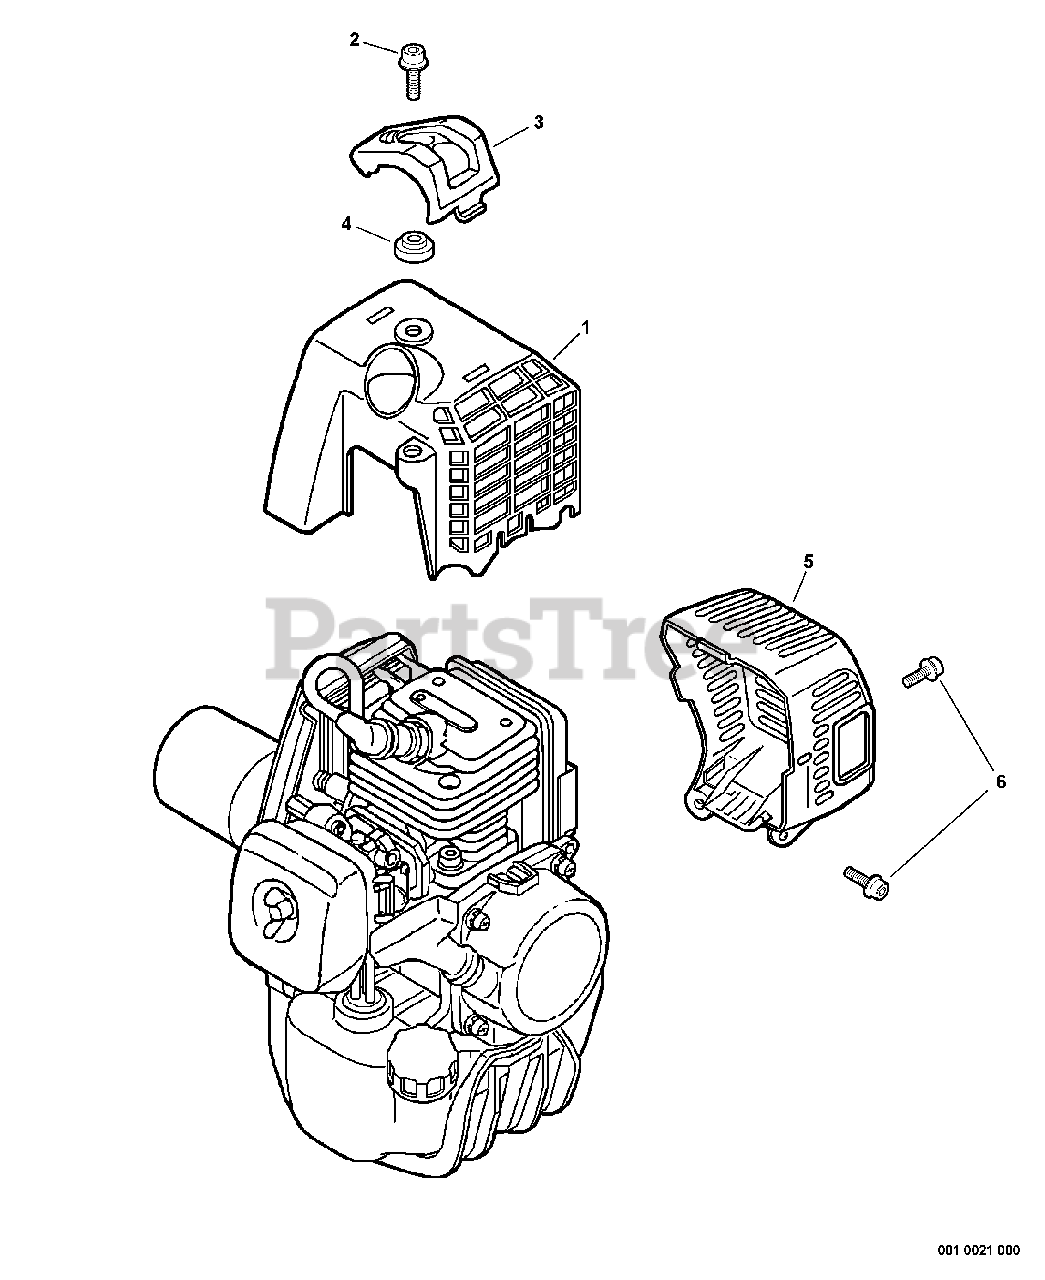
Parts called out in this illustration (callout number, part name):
1	COVER, ENGINE - ORANGE
2	BOLT 5×16
3	GUARD, TOP
4	COLLAR 5
5	COVER, MUFFLER
6	BOLT 5×12
